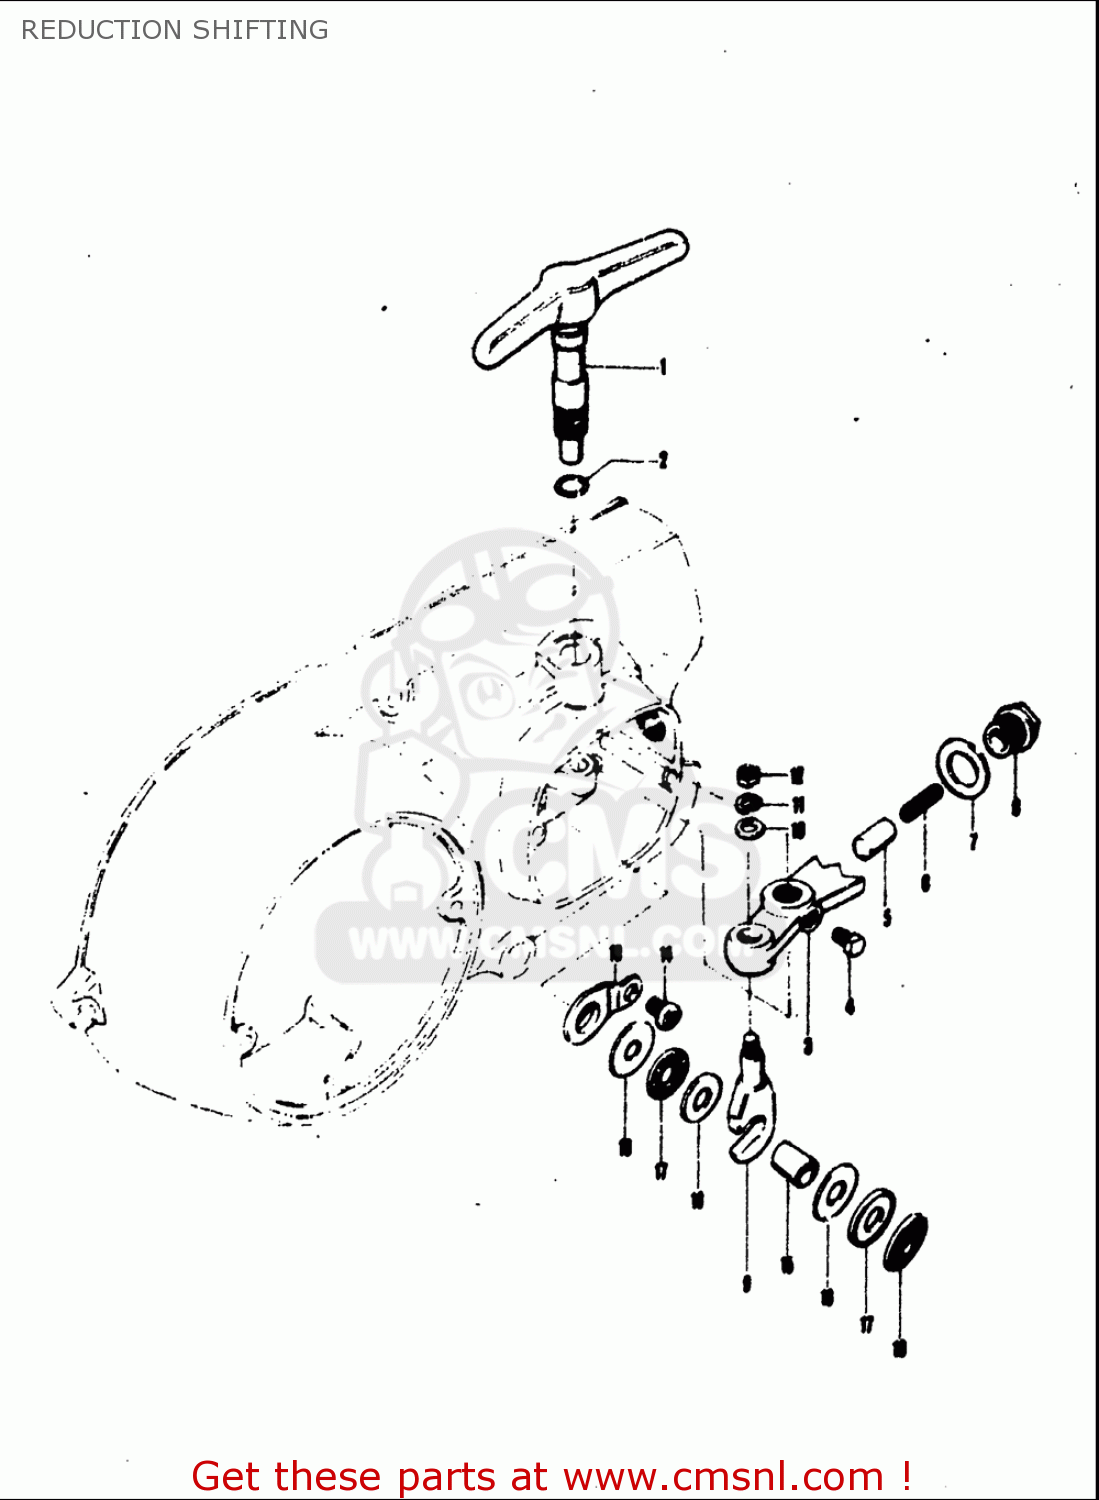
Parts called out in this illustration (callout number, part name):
2	O RING(D:1.3,ID:9.6)
5	STOPPER,REVERSE CAM
6	SPRING
7	WASHER(14.5X22X1)
10	WASHER
11	WASHER,LOCK
12	NUT
15	SPACER(6X10X12.2)
16	WASHER(10.5X18X1)
17	BEARING(10X22X2.8)
18	WASHER
19	WASHER (6X22X2)
